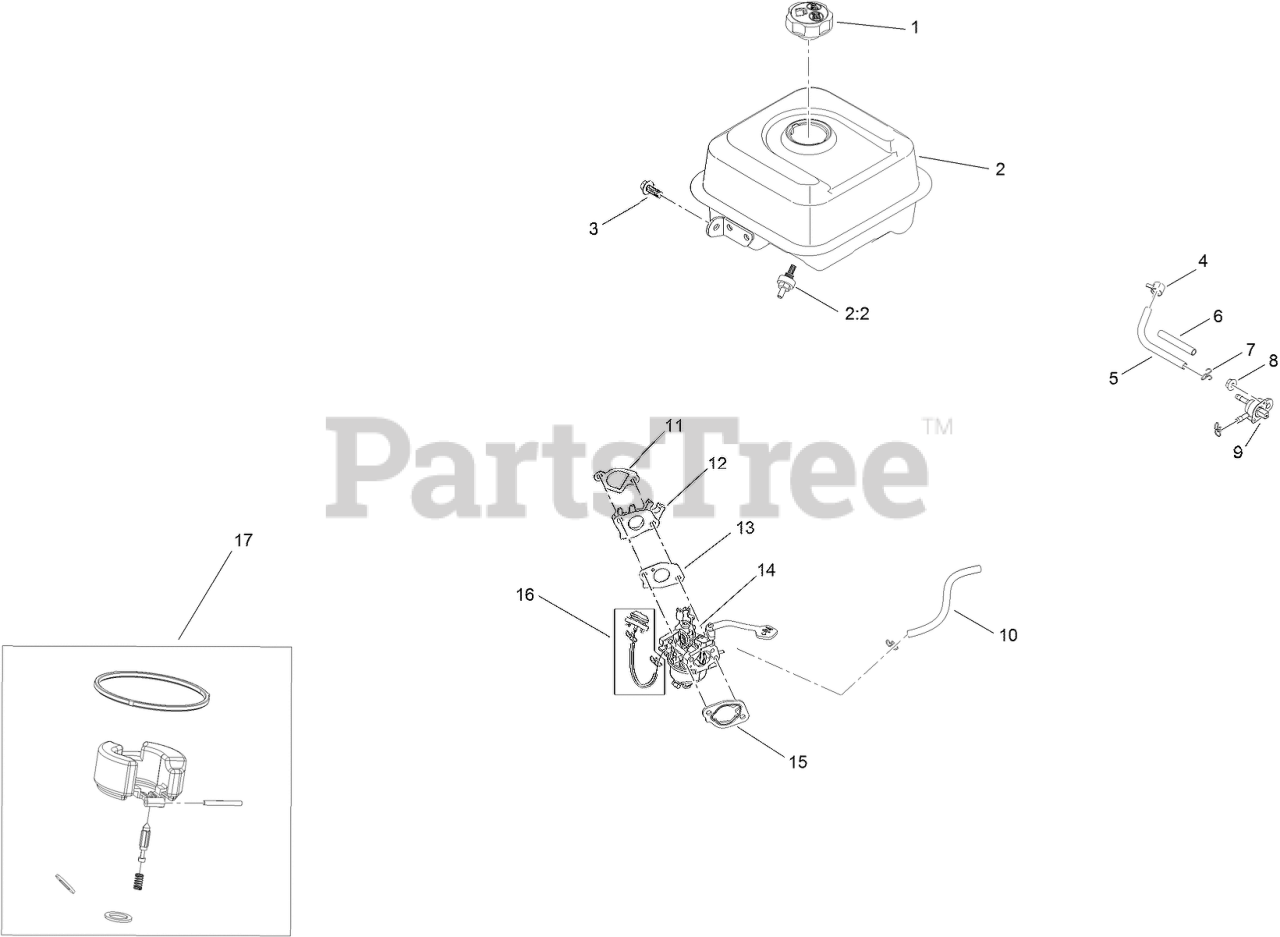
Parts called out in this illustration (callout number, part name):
1	CAP-FUEL (PHASE 3)
2	FUEL TANK AND FILTER ASM
2:2	FILTER-FUEL
3	SCREW-HHF
4	CLAMP-HOSE
5	HOSE-FUEL
6	SLEEVE-ABRASION
7	CLAMP-HOSE
8	NUT-FLANGE
9	VALVE-FUEL
10	HOSE-FUEL
11	GASKET-CARBURETOR
12	INSULATOR-CARBURETOR
13	GASKET-CARBURETOR
14	CARBURETOR ASM
15	GASKET-CARBURETOR
16	PRIMER KIT
17	INTERNAL CARB SERVICE KIT
